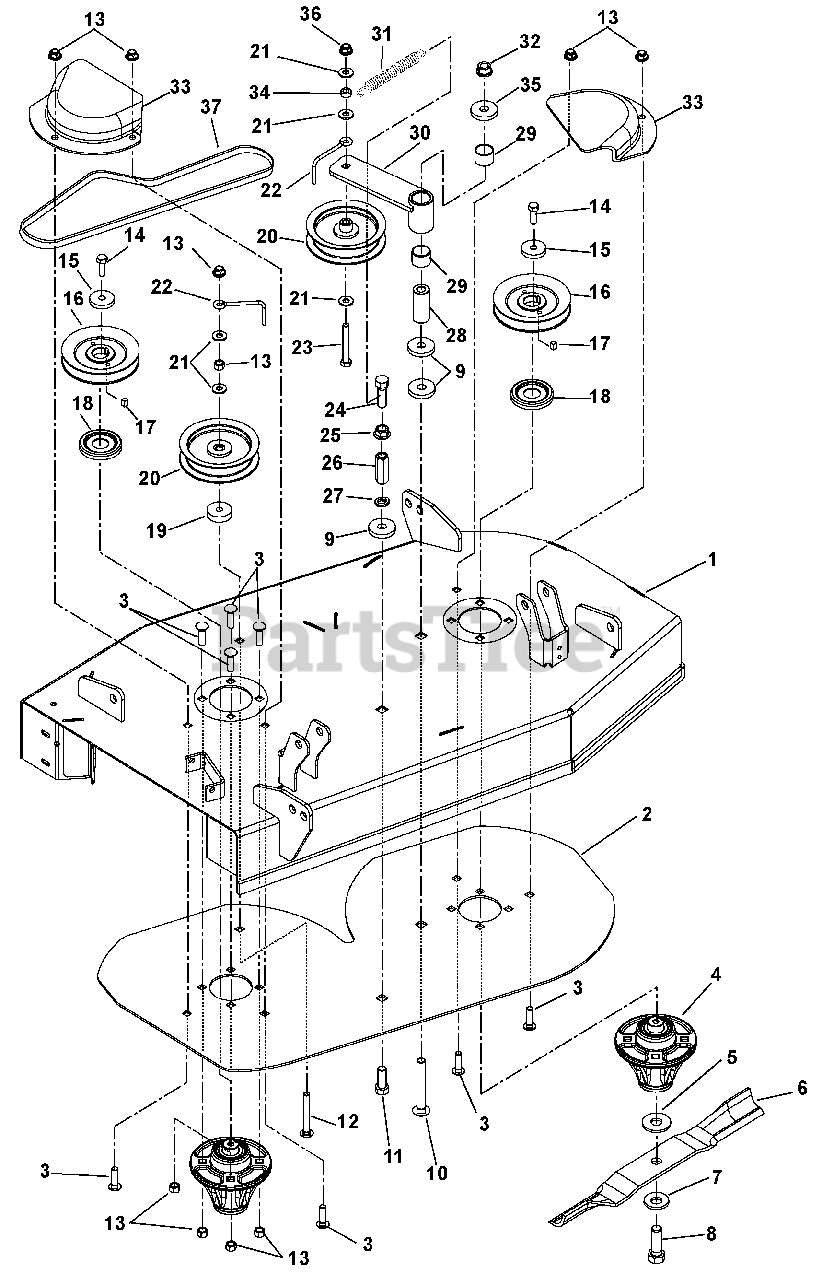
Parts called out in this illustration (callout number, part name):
1	Weldment, 34" Fabricated Deck
2	Plate, 34" Doubler
3	Bolt, Round Head Square Neck .38-16 x 1.25 Grade 5
4	Spindle Assembly
5	Washer, Flat - Steel .688 x 1.75 x .134
7	Washer, Flat - Steel .63 x 1.625 x .14
8	Bolt, Hex .62-18 x 1.75 Grade 8
9	Washer, Flat - Steel .515 x 1.625 x .250
10	Bolt, Round Head, Square Neck .50-13 x 3.50 Grade 5
11	Bolt, Round Head Square Neck .50-13 x 1.25 Grade 5
12	Bolt, Round Head Square Neck .38-16 x 2.75 Grade 5 Full-Length Thread
13	Nut, 038-16 Nyloc Flange
14	Bolt, Hex .38-16 x 1.00 EP30
15	Washer, Flat - Steel .406 x 1.50 x .245
16	Sheave, 4.75 Diameter A-Section
17	Key, Square .25 x .38
18	Dust Cap
19	Spacer, .39 x 1.50 x .380
20	Idler, Flat .38 x 4.00 x 1.06
21	Washer, Flat - Steel .38 x .875 x .083
22	Belt Finger
23	Bolt, Hex .38-16 x 2.25 Grade 5
24	Bolt, Hex .50-13 x 1.50 Grade 5
25	Nut, Spin Lock, Flange .50-13
26	Nut, Coupling .50 x 1.75
27	Washer, Locking .50 x .125 Regular
28	Bushing, Spacer .505/.500 x .999/.996 x 2.05 x 2.03
29	Bearing, 1.00 x 1.12 x .75
30	Idler Arm
31	Spring, Extension
32	Nut, Locking, Top - Flange .50-13
33	Belt Cover
34	Bushing, Sleeve .377 x .624 x .235
35	Washer, Flat-Steel .563 x 1.38 x .109
36	Nut, Locking Center .38-16
37	Belt, HA 97.00 Wrapped
